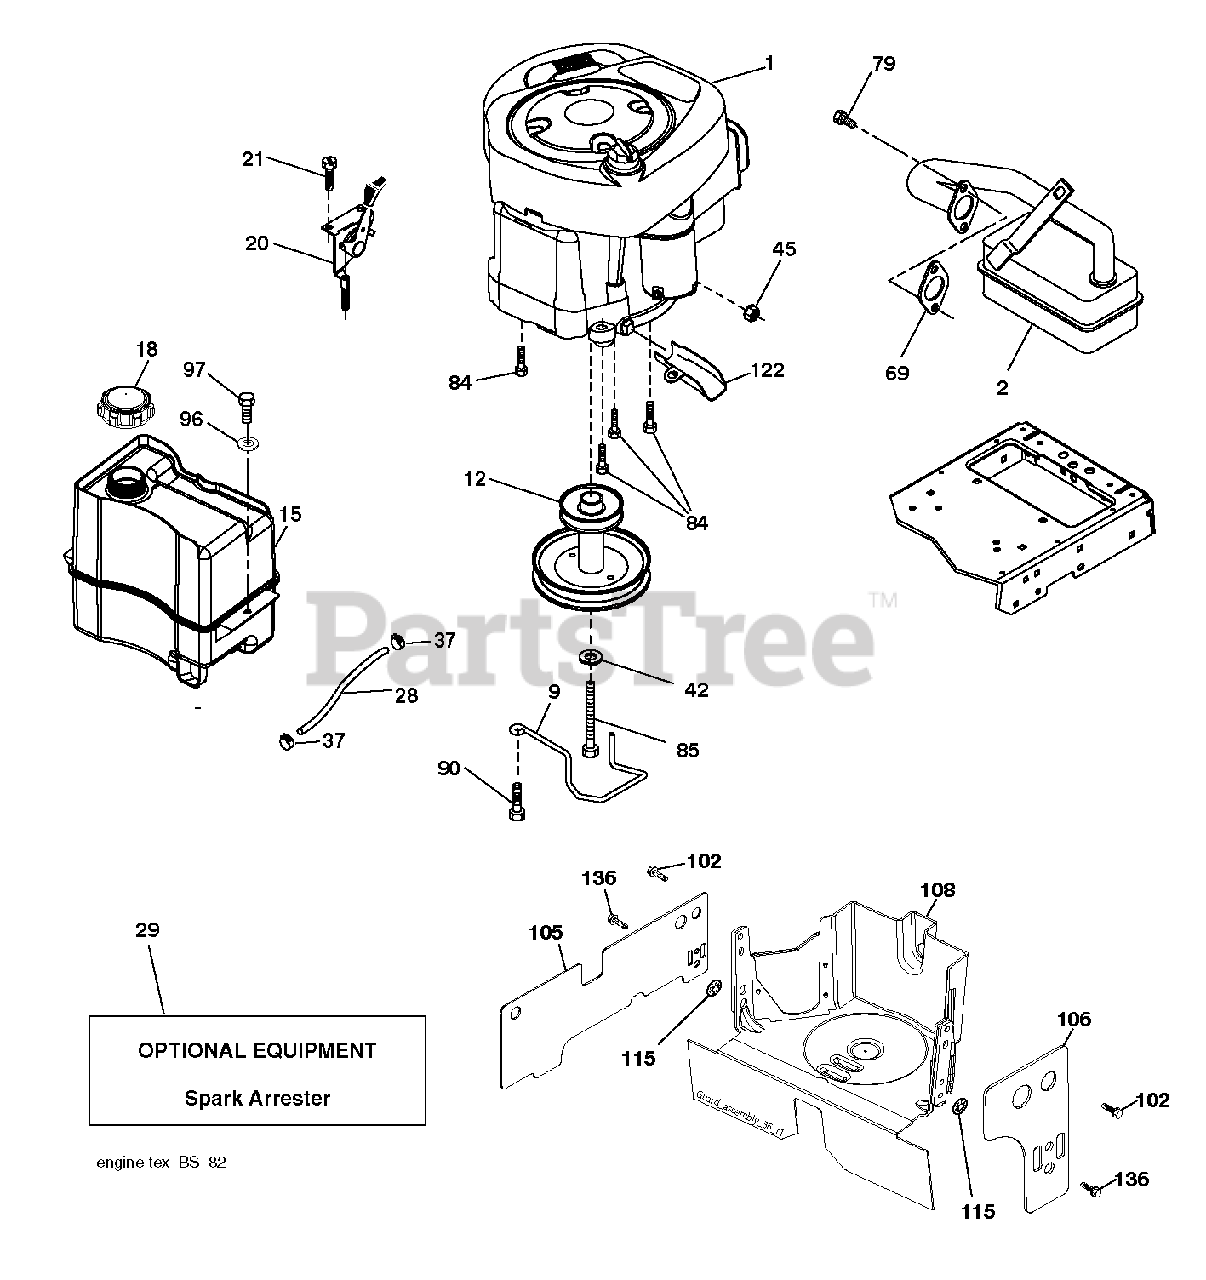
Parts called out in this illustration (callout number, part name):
2	MUFFLER.B&S.MODEL.21.11HP.OHV
9	KEEPER.BELT.ENGINE.3.25 (3 2)
12	PULLEY.ENG.CL.MECH.SLVR.LT/YT
15	FUEL.TANK.ASM.NON-EPA
18	CAP ASM.FUEL.2.25"FR.
20	CONTROL.TH/CK.C.
21	SCREW.#10 X 0.750.BOS
28	LINE.FUEL.20
29	KIT.SPARK ARRESTOR 794945 B&S
37	HOSE CLAMP
42	LOCKWASHER
45	NUT
69	REPL BY 532 27 22-93
79	SCREW.SOCKET HD.5/16-1
84	SCREW.3/8-16
85	BOLT HEX 7/16-20X4-1/4"
90	SCREW 3/8-16X1
97	SCREW HEXWSHR 1/4-20X3/4
102	SCREW
105	SHIELD LEFT
106	SHIELD SIDE
108	COVER PULLEY
115	PALNUT 1/4
122	EXTENSION DRAIN OIL
136	SCREW.1/4-20X5/8
